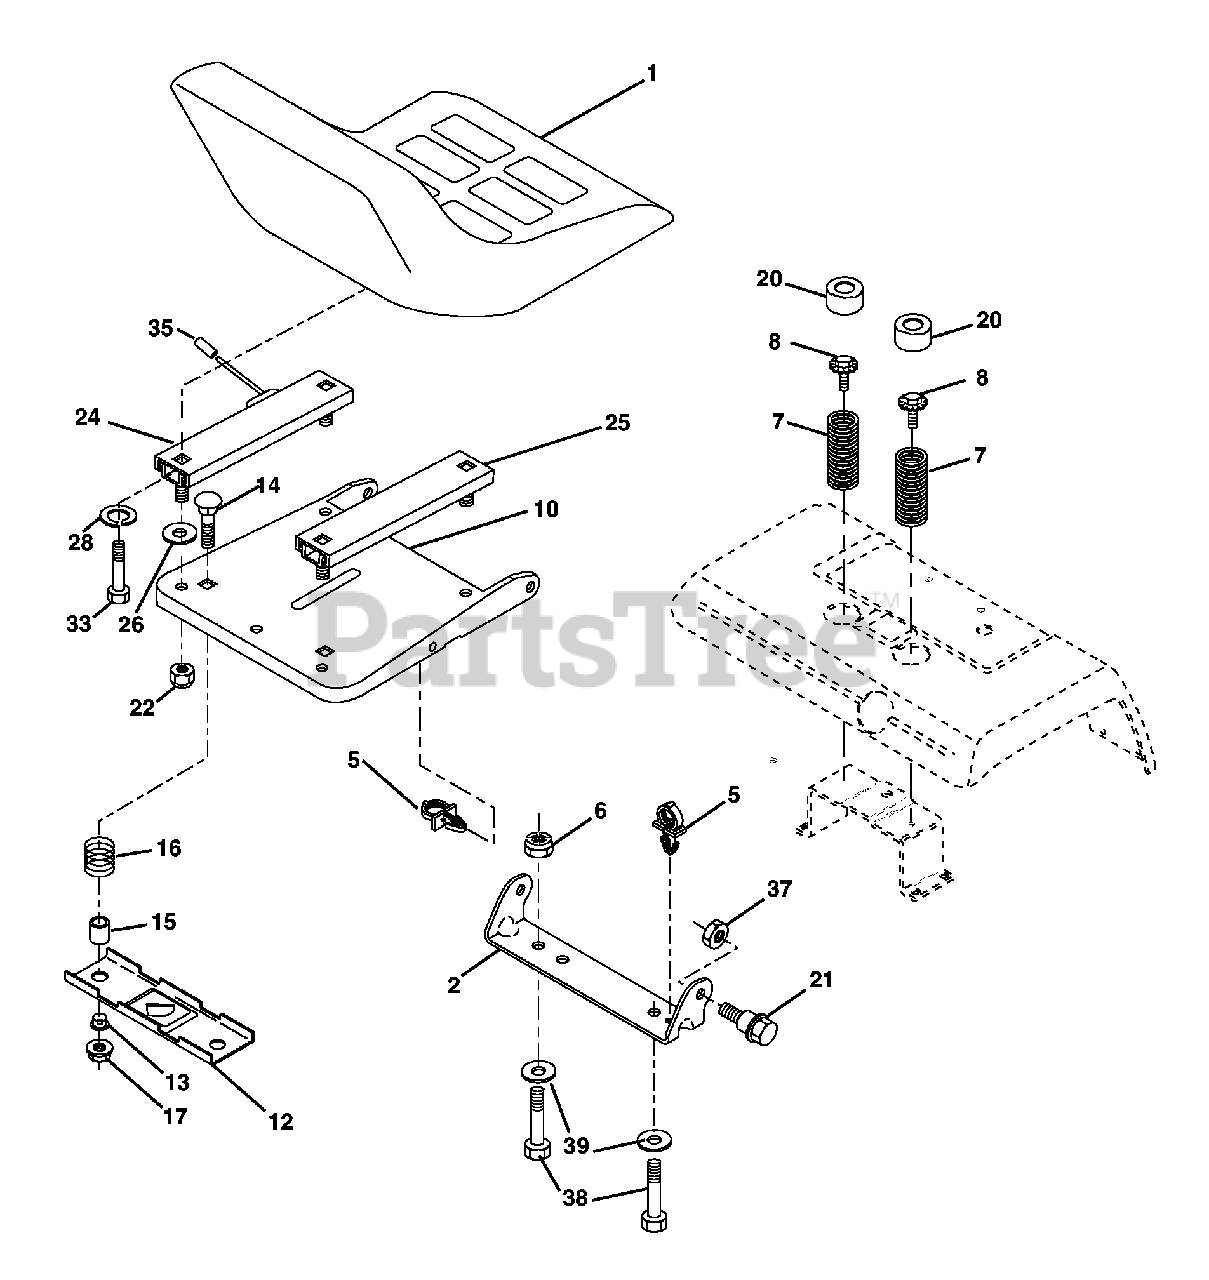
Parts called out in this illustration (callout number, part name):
1	Seat
2	Bracket, Pivot Seat
5	Clip, Push In Hinged
6	Nut, Crownlock 3/8-16
7	Spring, Seat Cprsn
8	Bolt 5/16-18 Unc x 3/4
10	Pan, Seat
12	Bracket, Mounting Switch
13	Bushing, Snap
14	Bolt, Carriage 1/4-20 x 1-1/2
15	Spacer, Split
16	Spring, Cprsn
17	Nut, Lock 1/4 Lge Flg Gr. 5
20	Cap, Spring Seat
21	Bolt, Shoulder 5/16-18
22	Nut, Crownlock 5/16-18
24	Track Slide Seat LH
25	Track Slide Seat RH
26	Washer 11/32 x 5/8 x 12 Ga.
28	Washer Split
33	Bolt Fin Hex 5/16-18 Unc x 3/4
35	Cap Vinyl 1 x .34 Red
38	Bolt 3/8-16 x 1
39	Washer 13/32 x 1 x 10 Ga.
